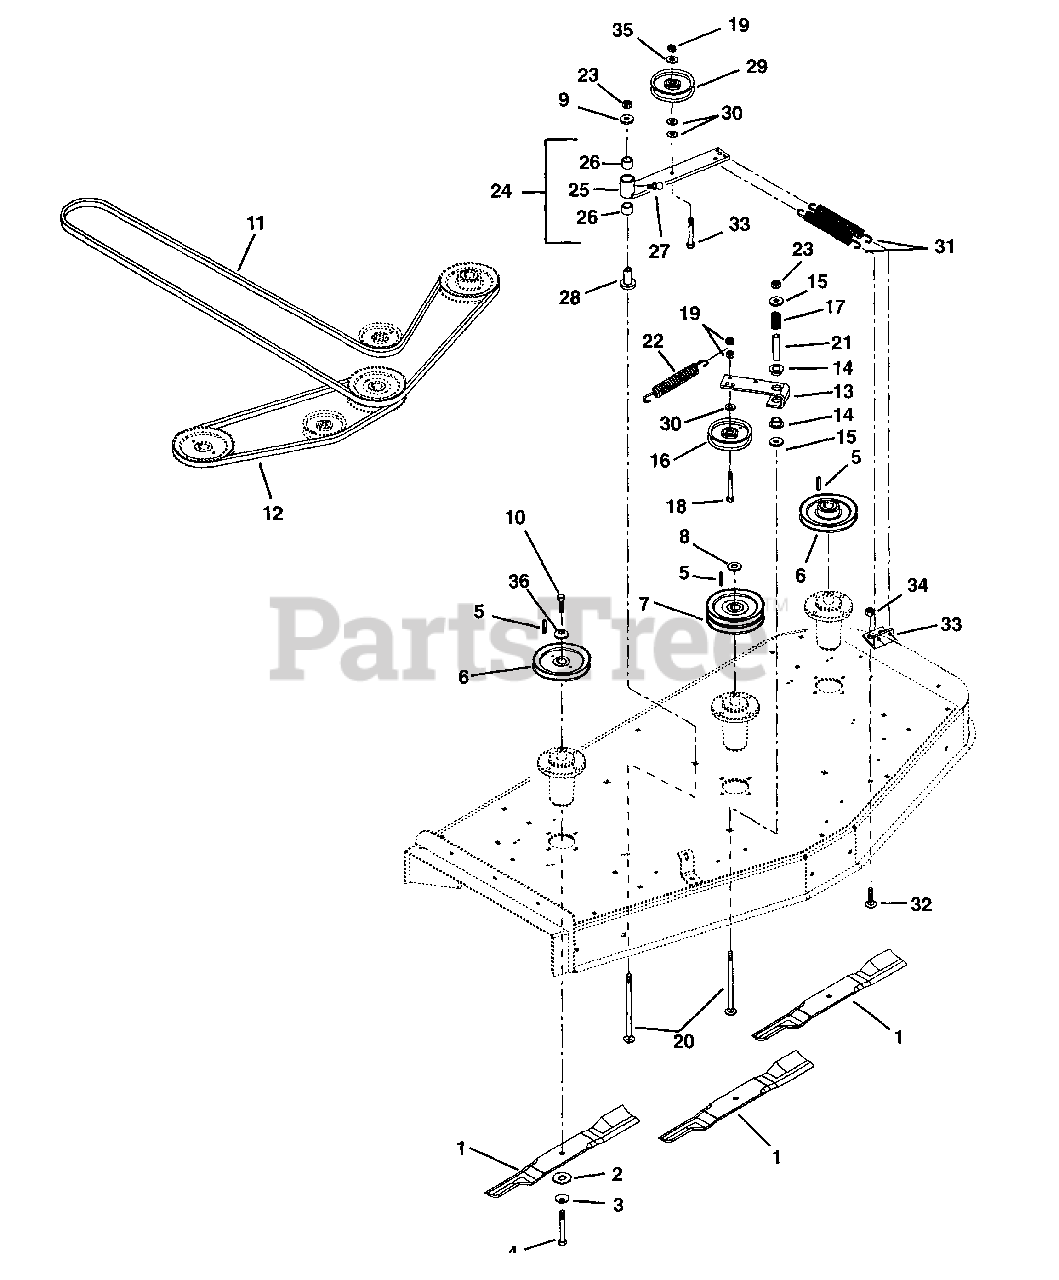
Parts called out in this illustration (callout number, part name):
1	Blade, 60" Mower Tungsten Hi-Lift
1	Blade, 50" Mower Tungsten Hi-Lift
2	Washer, Flat .640 x 1.81 x .250
3	Washer-Bellville .63 x 1.625 x .14
4	Bolt, Blade
5	Key-Straight .25 x .75 x .25
6	Weldment, Spindle Sheave 6.00 (60" Deck)
6	Weldment, Spindle Sheave 5.00 (50" Deck)
7	Weldment, Spindle Sheave (Double) 6.00 (60" Deck)
7	Weldment, Spindle Sheave-Double 5.00 (50" Deck)
8	Washer, Cupped, Serrated .375
9	Washer-Flat-Steel .531 x 1.250 x .100
10	Bolt-Hex .38-16 x 1.00 Grade 5
11	V-Belt, B-RMA 63.40 x .625 (60" Deck)
11	V-Belt, B-RMA 58.70 x .625 (50" Deck)
12	V-Belt, B-RMA 23.94 x .625 (60" Deck)
12	V-Belt, B-RMA 18.13 x .625 (50" Deck)
13	Arm,Idler Pivot
14	Bushing-Flange .762 x 1.0 x .580 x 1.48 Nylon
15	Washer-Flat-Steel .531 x 1.250 x .100
16	Idler-V 4.00 x .377
17	Spring-Compression .085 x .80 x 1.00 WLD 36
18	Bolt-Hex .38-16 x 2.25 Grade 5
19	Nut-Locking-Center .38-16
20	Bolt-Round Head Square Neck .50-13 x 3.50
21	Spacer .560 x .750 x 2.437 Steel
22	Spring, Extension
23	Nut-Locking-Center .50-13
24	Assembly, Idler Pivot Arm
25	Weldment, Idler Pivot Arm
26	Bearing 1.000 x 1.125 x 1.00
27	Fitting-Lube .25-28 x,256
28	Bearing, Pedistal Powdered Metal
29	Idler-Flat 4.00 x .38 (2.00 W)
30	Bushing .406 x .750 x .188
31	Spring, Extension
32	Bolt-Round Head Square Neck .31-18 x .75 Grade 5
33	Bracket, Spring
34	Nut-Locking-Nylon .38-16
35	Washer-Flat-Steel .406 x .812 x .065
36	Washer-Flat-Steel .406 x 1.00 x .188
37	50" Mulching Blade-Tungsten
38	60" Mulching Blade-Tungsten
